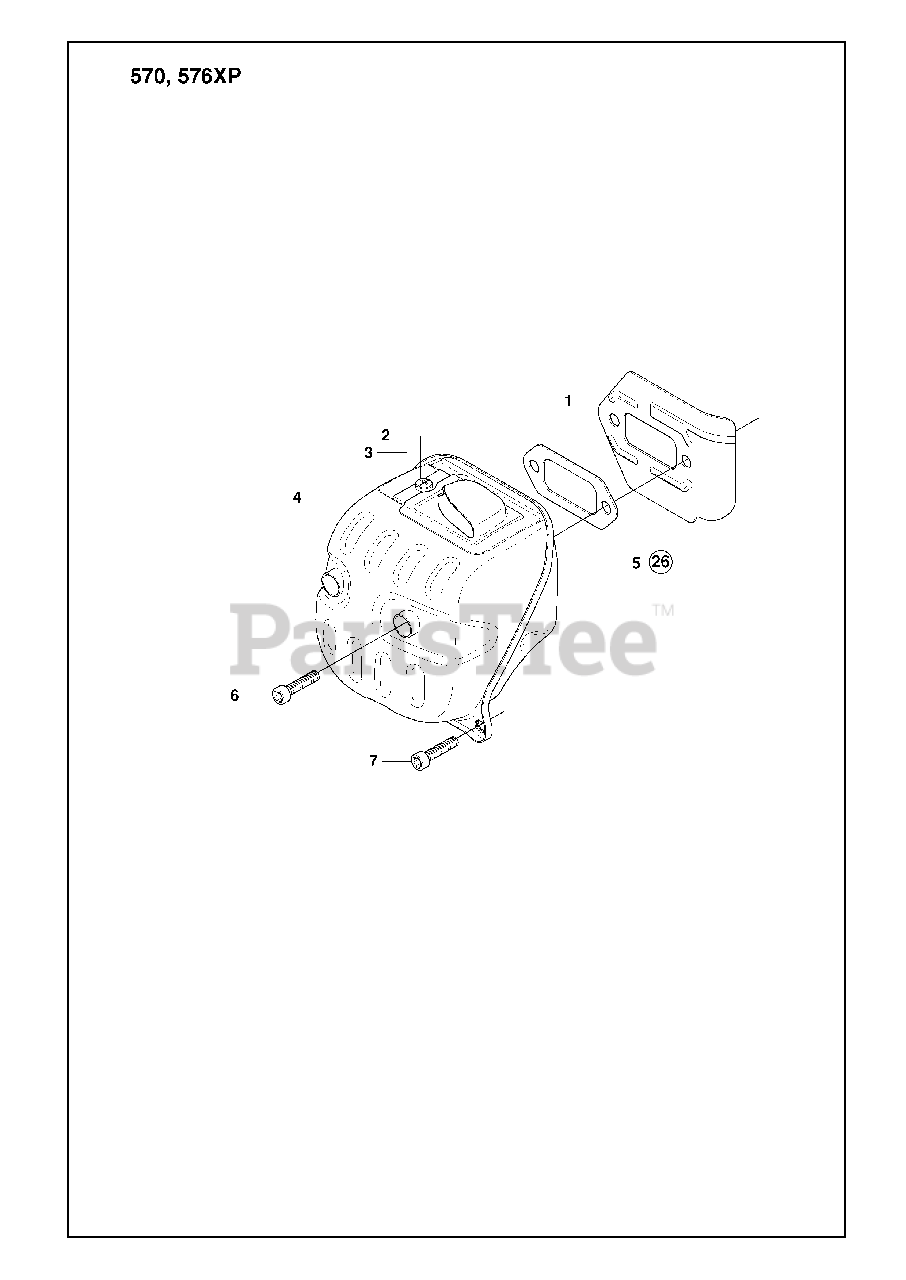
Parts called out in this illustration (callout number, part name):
4	MUFFLER ASSY (FF CE)
4	MUFFLER ASSY (DF US)
6	SCREW MC6S 6X20
26	GASKET SET
26	GASKET KIT
